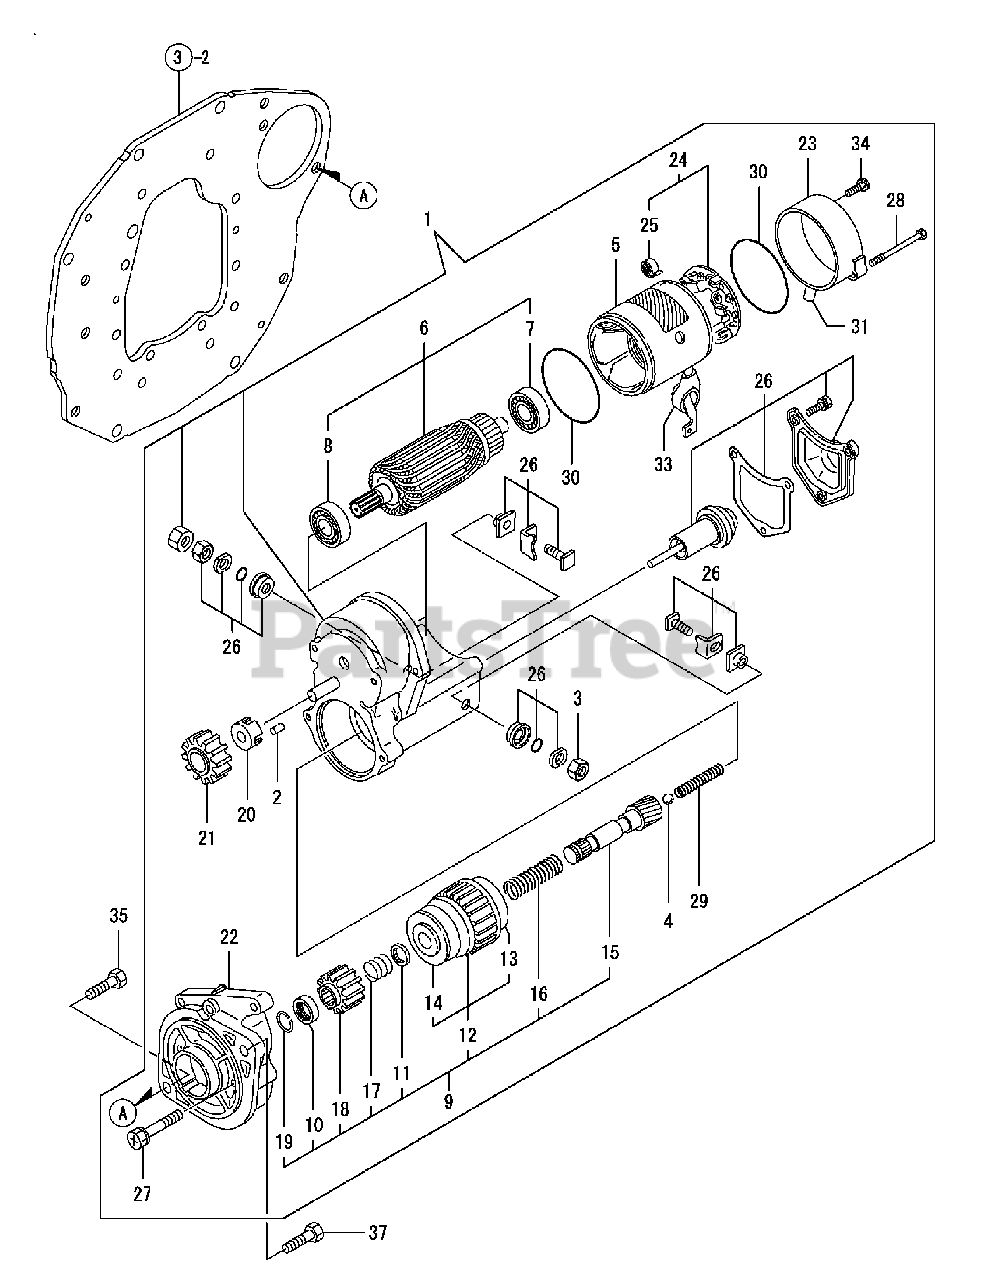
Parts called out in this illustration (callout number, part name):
1	STARTER, RA1.4
11	RETAINER, SNAP
12	CLUTCH ASSY, STARTER
18	PINION, STARTER
37	BOLT M12X 20 PLATED
